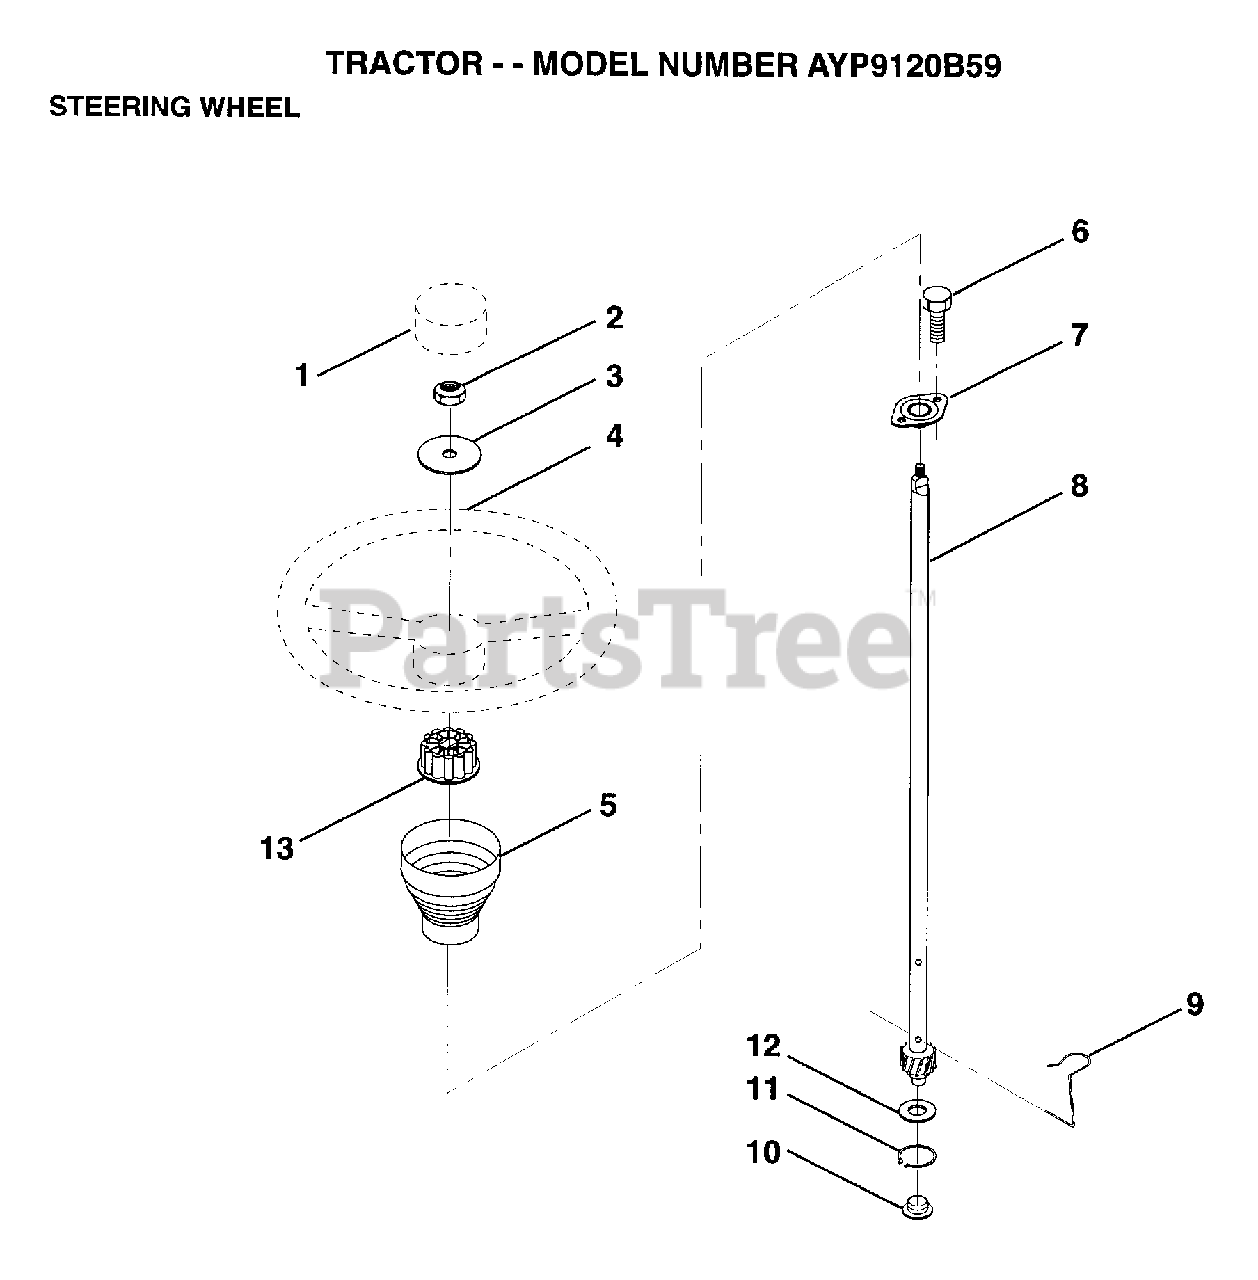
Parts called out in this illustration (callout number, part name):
1	ST WHL INSERT CAP
2	GRIPCO NUT
3	WASHER T
5	SLEEVE STEERING
9	STEERING CLIP
10	BUSHING STEER LWR
11	RING
12	WASHER LT
13	ADAPTER-WHEEL LT
